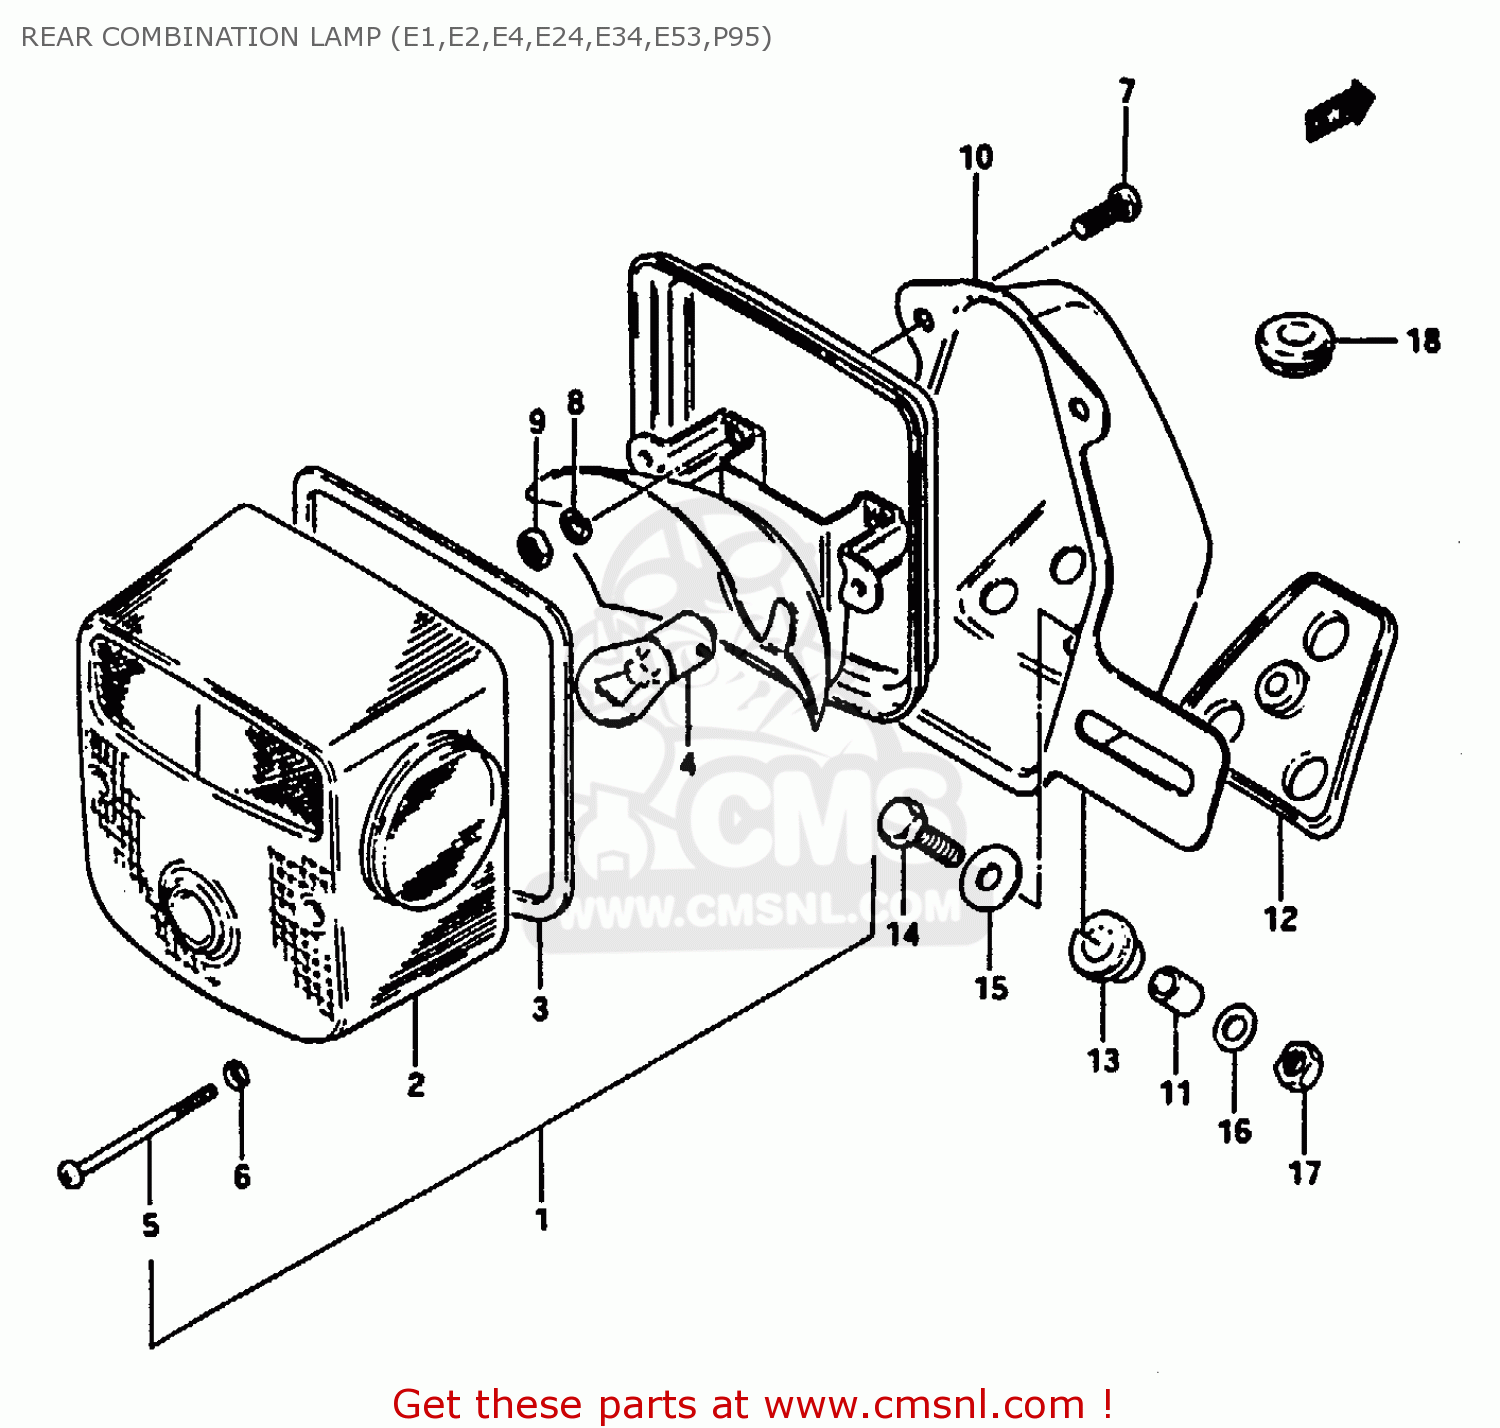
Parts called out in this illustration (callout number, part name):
1	LAMP UNIT,TAIL
2	LENS
3	GASKET (NAS)
4	BULB(12V23W)
5	SCREW (4X55)
6	GASKET (NAS)
7	SCREW 6X12
8	WASHER,LOCK
9	NUT
10	BRACKET UNIT,TAIL LAMP
11	SPACER
12	CUSHION
13	CUSHION
14	BOLT
15	WASHER (6.5X20X1.2)
16	WASHER
17	NUT
18	GROMMET
